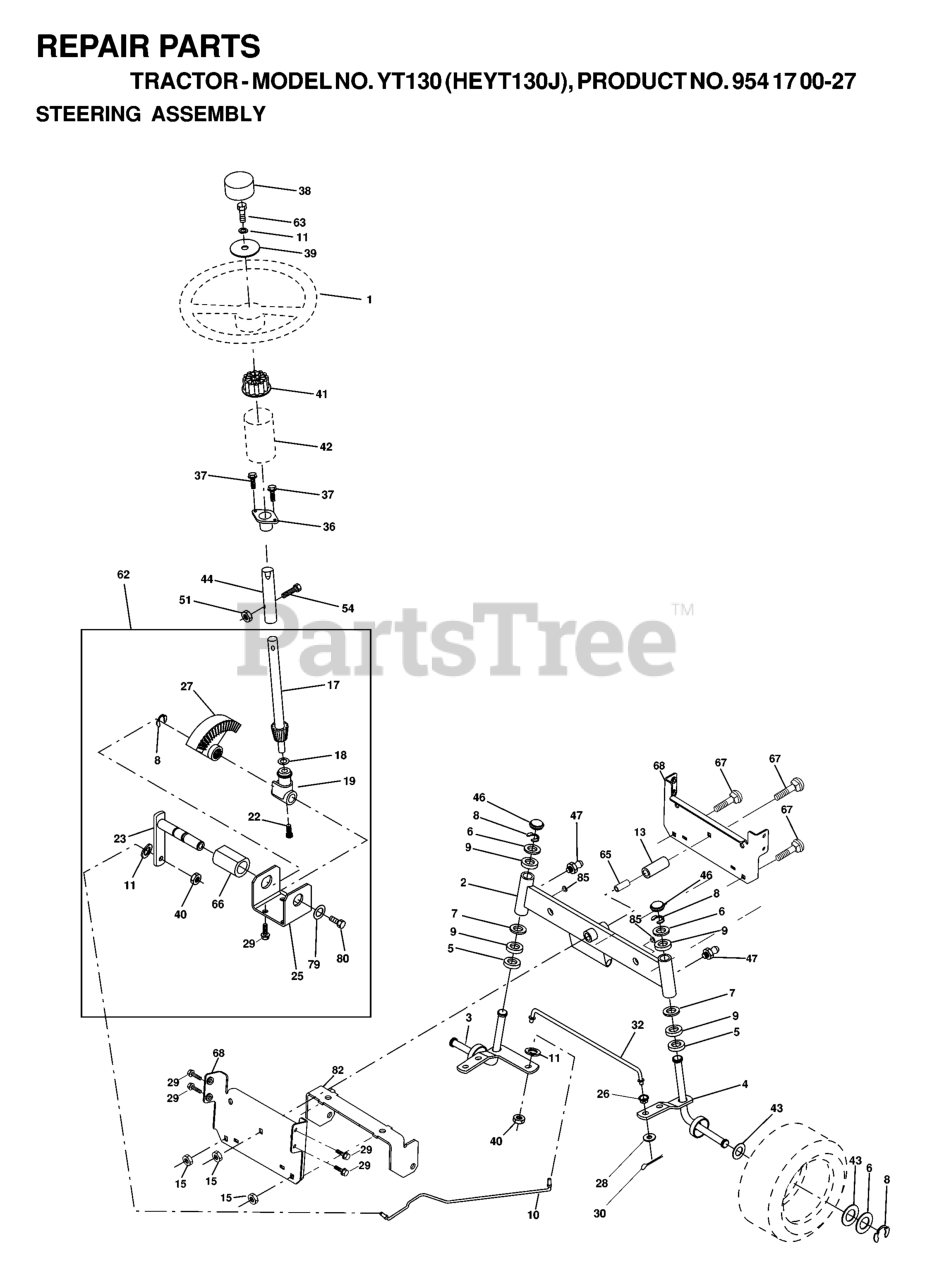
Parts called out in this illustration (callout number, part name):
1	STEERING WHEEL
2	AXLE ASSY
3	SPINDLE.ASM.LH.15"TIRES
4	SPINDLE.ASM.RH.15"TIRES
5	THRUST WASHER
9	BRNG T
10	DRAGLINK.15".TIRES
11	WASHER, LOCK 3/8
13	TUBE, PIVOT AXLE
15	NUT
17	SHAFT ASM STEERING
18	THRUST WASHER
19	STEERING SHAFT SUPPORT
22	SCREW.HX.WSH.HD
23	SHAFT ASSY PITTMAN
25	BRACKET STEERING
26	BUSHING.DRAGLINK (2 2)
27	GEAR.SECTOR
28	WASHER
29	SCREW 3/8-16X3/4
30	COTTER PIN
32	TIE ROD
36	BUSHING, STEERING
37	SCREW.TT.#10-32X.5.3/8.FLANGE
38	CAP.WHEEL.STEERING.GREY
39	Washer 13/32 x 1-1/20 x 11 Gauge
40	GRIPCO NUT
41	STEERING WHEEL ADAPTOR
42	BOOT STEERING
44	EXT SHAFT STEERING
46	CAP.SPINDLE.BLACK
47	ZERK M
51	NUT.71038.31-18.HEX.NYLOCK
54	BOLT.5/16-18X1-1/4 FULL.THREAD
62	STEERING KIT
65	SPACER BRACE AXLE
66	BEARING ARM
67	BOLT CARRIAGE
68	BRACE.AXLE.15"TIRES
79	WASHER
80	BOLT.HX.NYLON3/8-16X
82	HOUR METER
85	FASTENER.XMAS.TREE
